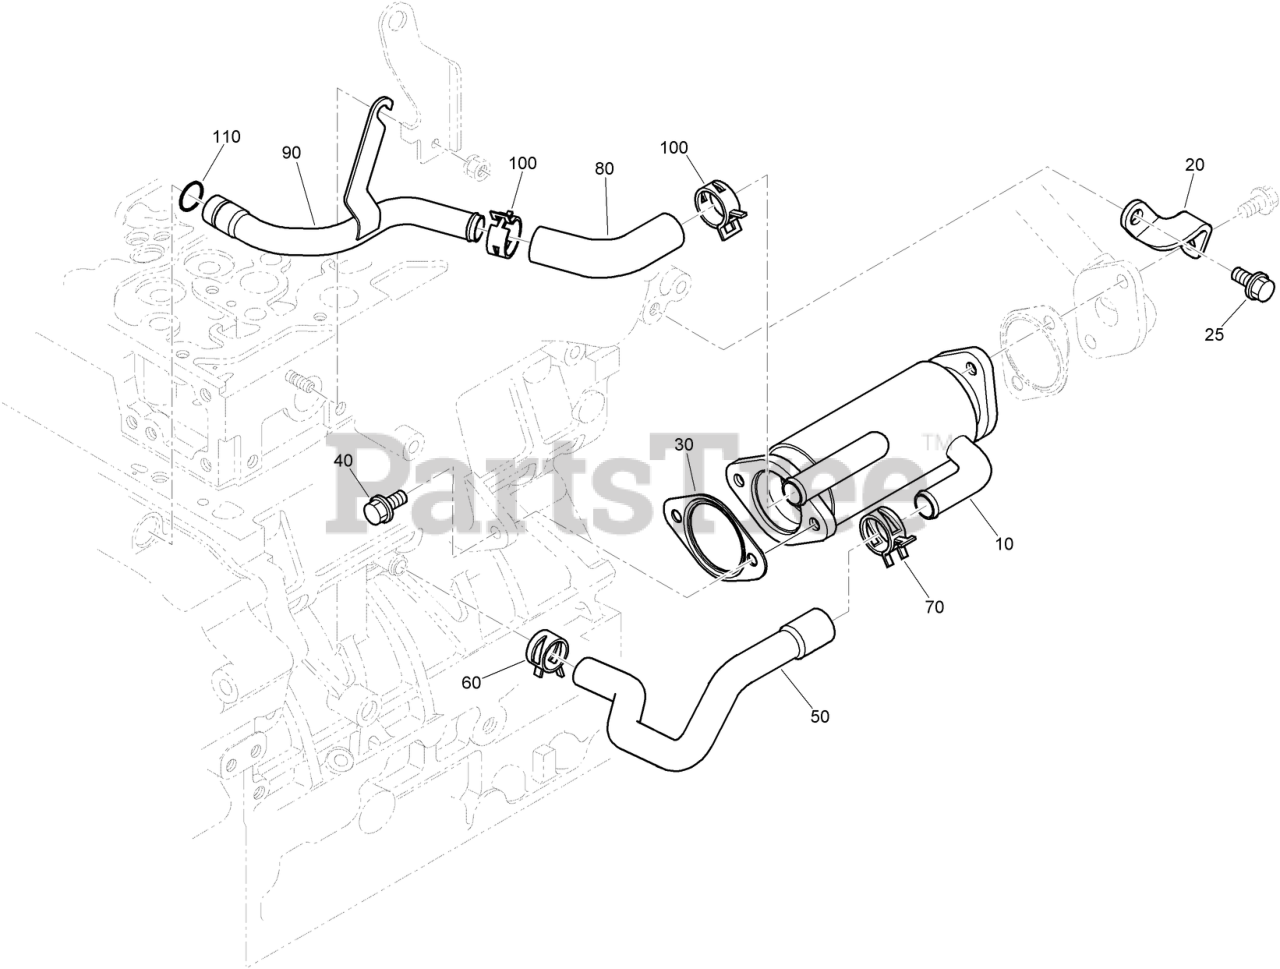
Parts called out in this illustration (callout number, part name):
10	COOLER-E G R
20	STAY-COOLER, E G R
25	BOLT-FLANGE
30	GASKET-COOLER, E G R
40	BOLT-FLANGE
50	HOSE-E G R, C1
60	CLAMP-HOSE
70	CLAMP-HOSE
80	HOSE-E G R C2
90	PIPE-E G R, C2
100	CLAMP-HOSE
110	O-RING
